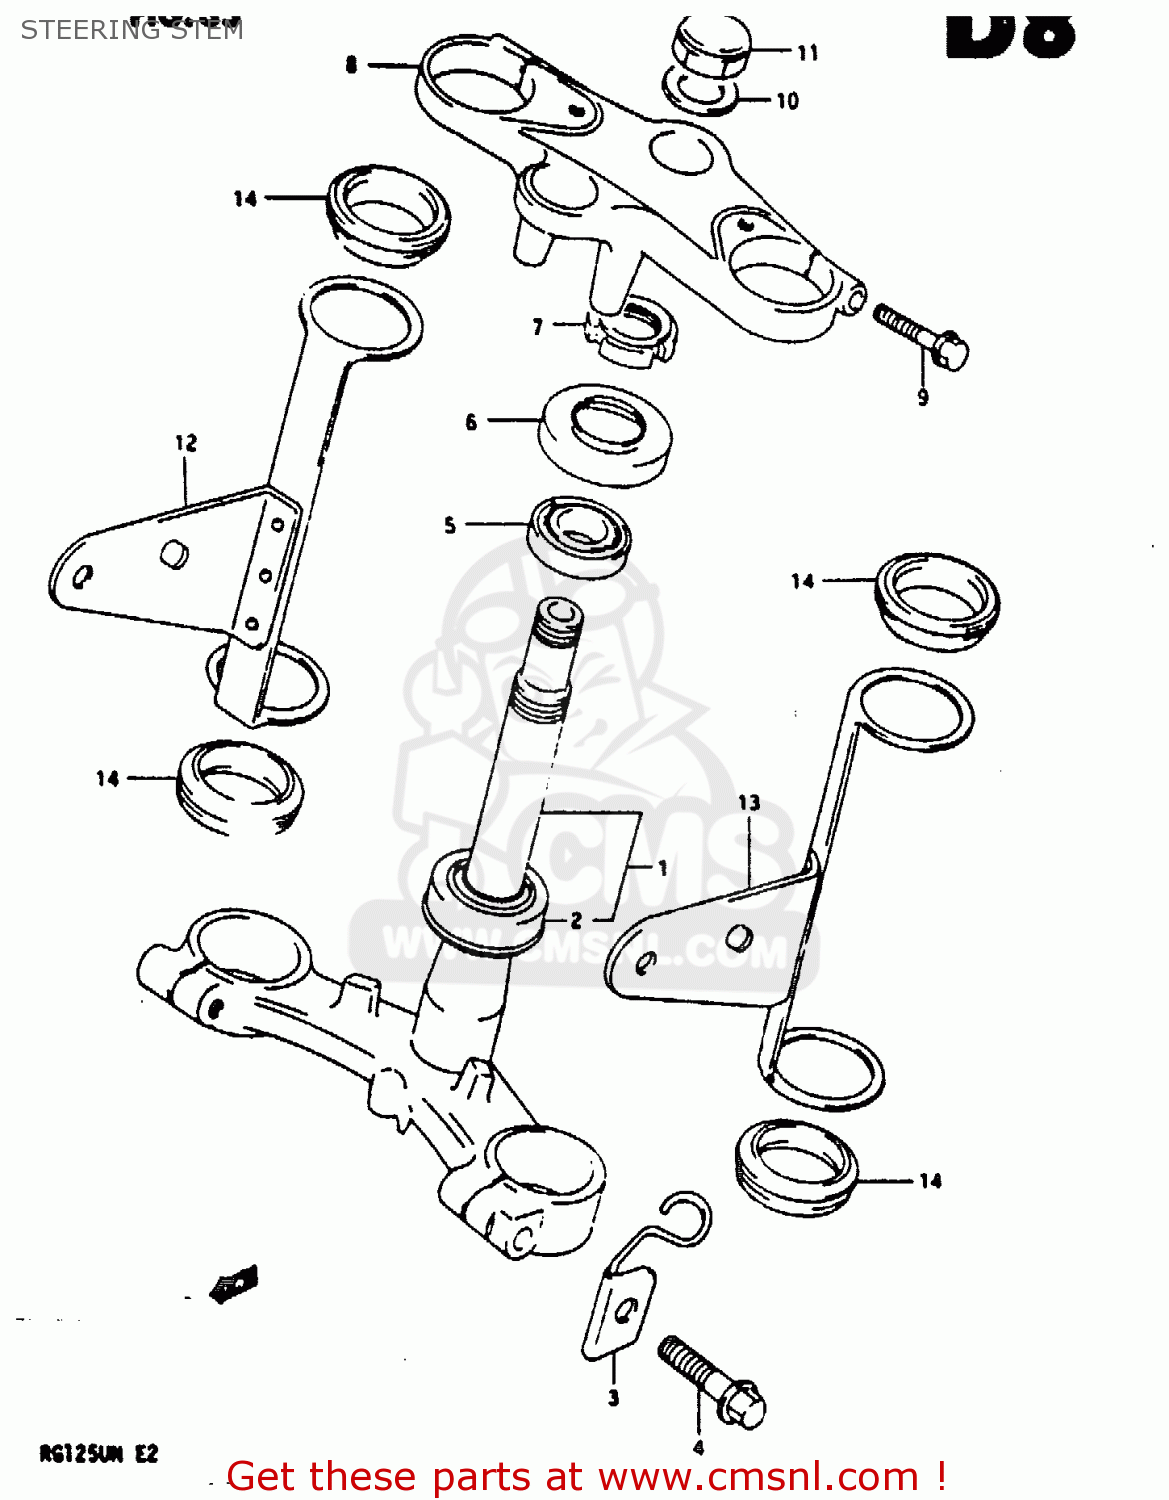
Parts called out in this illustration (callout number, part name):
1	STEM,STEERING
2	BEARING(30X55X17)
3	CLAMP,SPEEDOMETER CABLE
4	BOLT
5	TAPER,ROLLER BEARING
6	DUST SEAL,STEERING,UPPER
7	NUT,STEERING STEM(25X44X10)
8	HEAD,STEERING STEM
9	BOLT
10	WASHER
11	NUT,STEM HEAD
12	BRACKET,HEADLAMP HOUSING,R
13	BRACKET,HEADLAMP HOUSING,L
14	CUSHION,HEADLAMP HSG BRACKET
